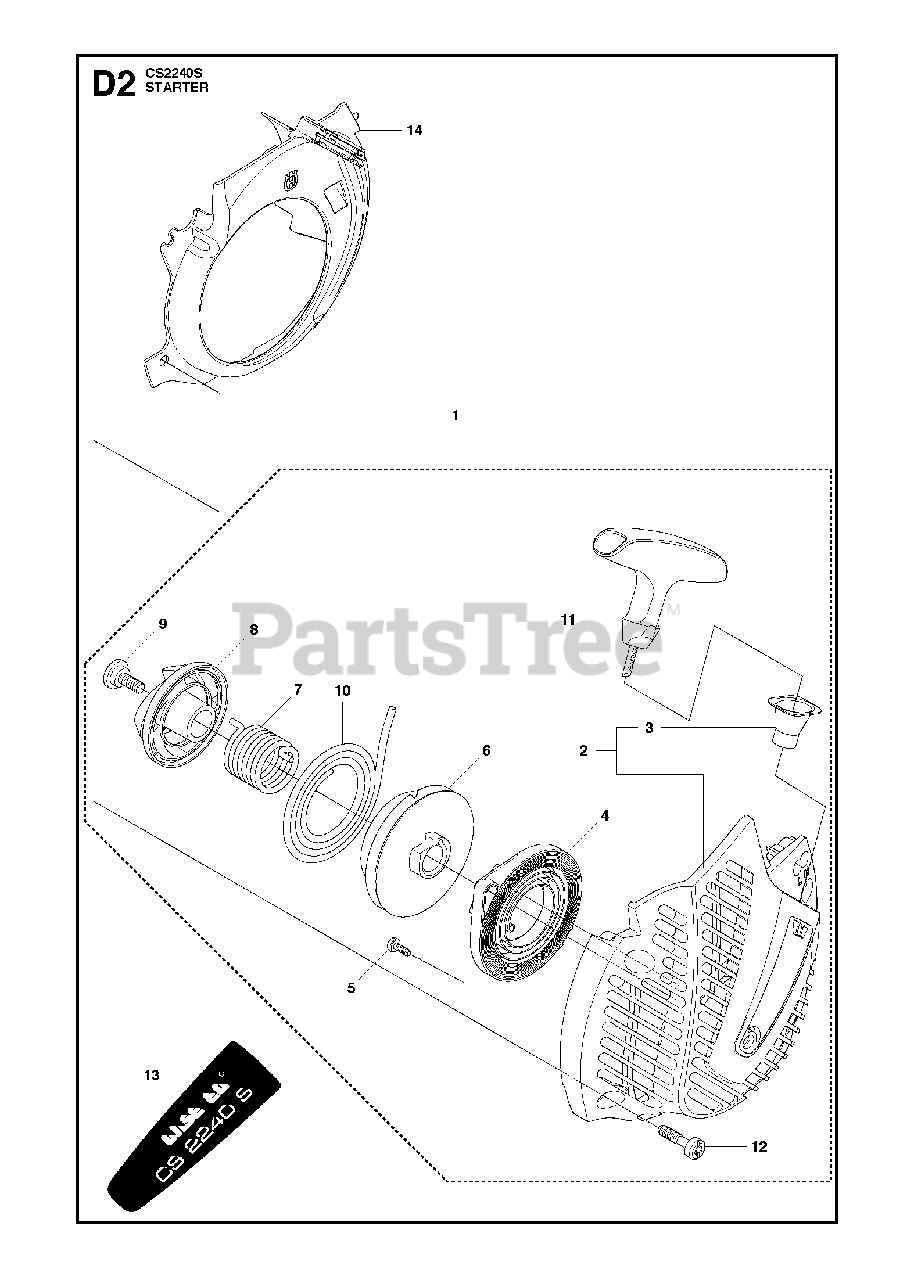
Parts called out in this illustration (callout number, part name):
1	STARTER
2	STARTER HOUSING
3	SLEEVE
4	SPRING CASSETTE ASSY
5	SCREW
6	STARTER PULLEY
7	SPRING
8	CARRIER
9	SCREW
10	STARTER ROPE
11	STARTER HANDLE
12	SCREW
14	%COOLING AIR CONDUCTOR
